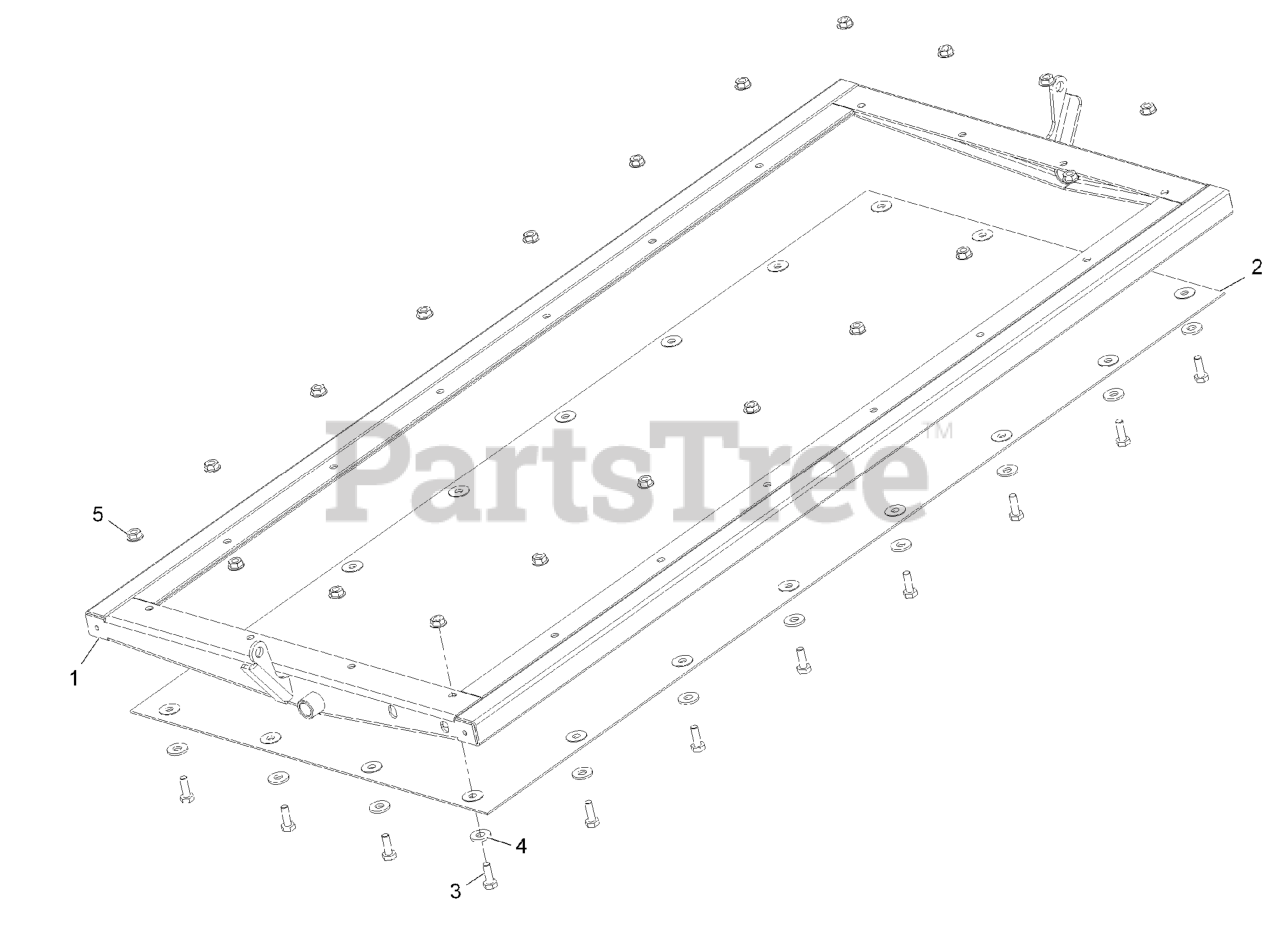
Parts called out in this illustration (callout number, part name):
1	DOOR-FRAME
2	SCREEN-DOOR
3	SCREW-HH
4	WASHER-FLAT
